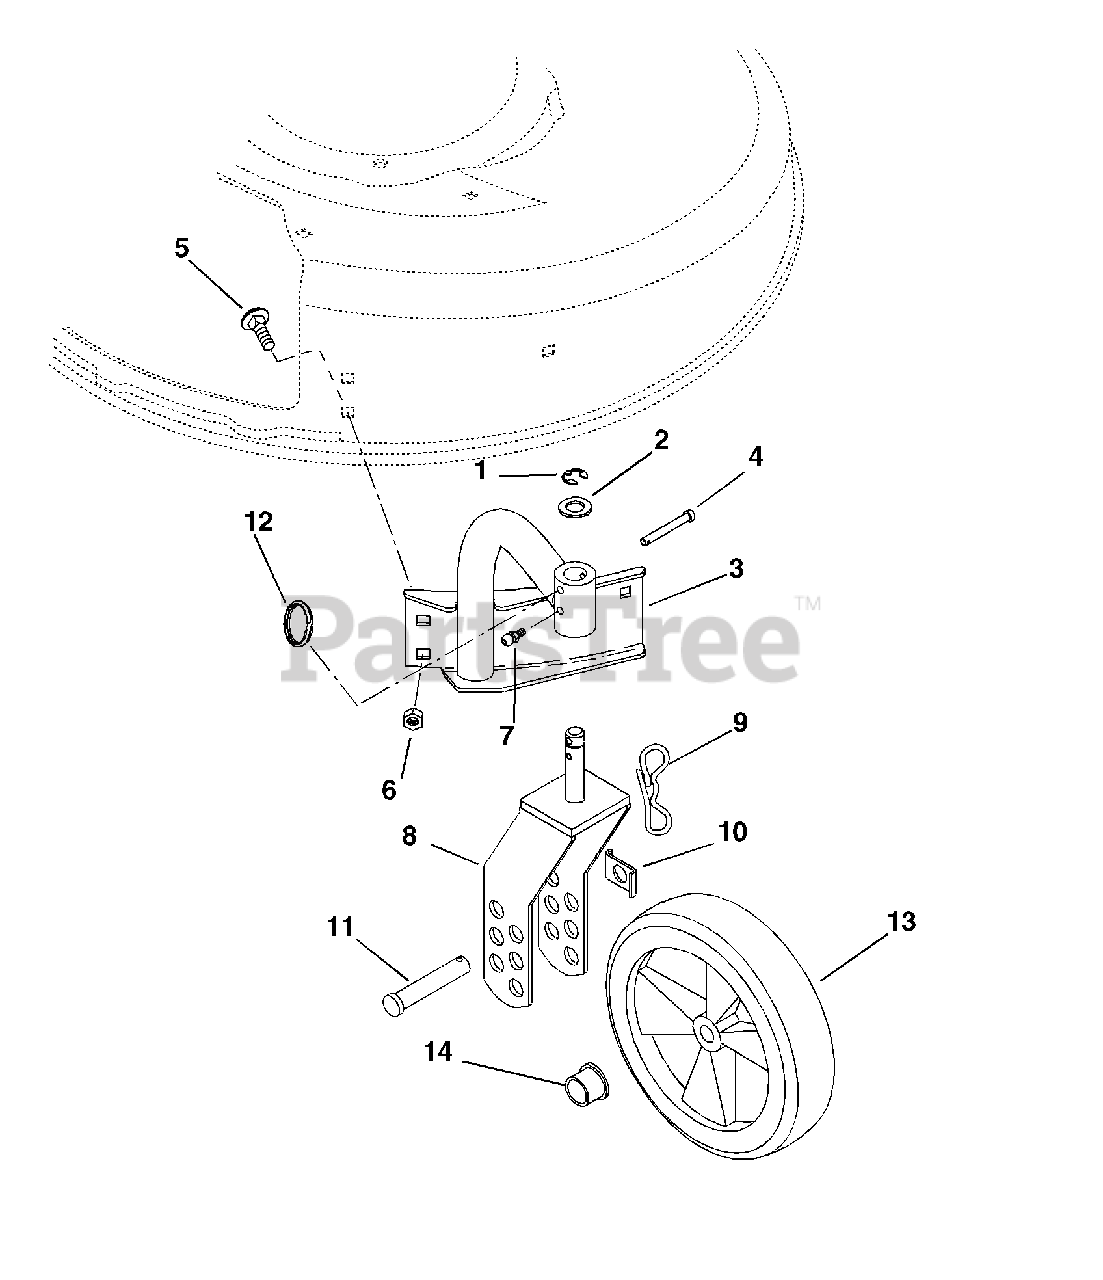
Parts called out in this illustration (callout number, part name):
1	RG-RTNG-EXT .625X.042
2	WSHR-FL-STL .630X1.005X.062 YZ
3	MOUNT, W/BSHG RIGHT ARM
4	PIN-CLEV .25X1.75 YWZC
5	@BLT-RDHDSQNK .31-18X.50 G5YZ
6	@NUT-SPNLK-FLG .312-18 YWZC
7	FTG-LUBE .25-28X.256 YWZC
8	WHEEL YOKE WELDMENT
9	PIN, BOWTIE COTTER
10	AXLE TAB
11	PIN-CLEV .494X2.62 YWZC
12	KICKOUT RING YWZC
13	WHL 7.50" .50 BORE, 1.50 HUB
14	BSHG-FLG .500X.625X.500X.750
